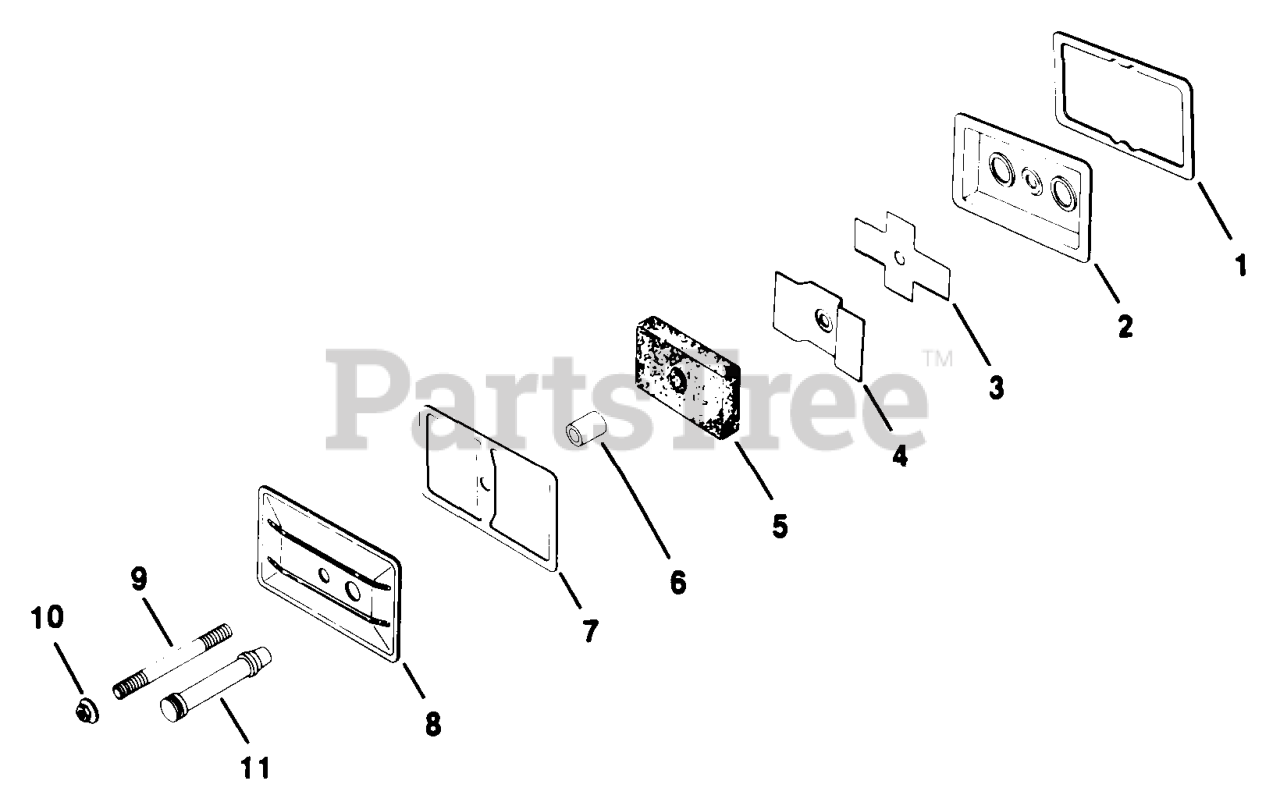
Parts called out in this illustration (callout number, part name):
1	GASKET, VALVE COVER
2	PLATE, BREATHER
3	REED, BREATHER - Use 47 402 01-S Breather Reed
4	BAFFLE, BREATHER
5	FILTER, BREATHER
6	SEAL, BREATHER
7	GASKET, VALVE COVER
8	COVER, VALVE
9	STUD, 1/4-20x3-1/4" - DISCONTINUED
10	PALNUT, 1/4-20
11	HOSE, BREATHER - DISCONTINUED
